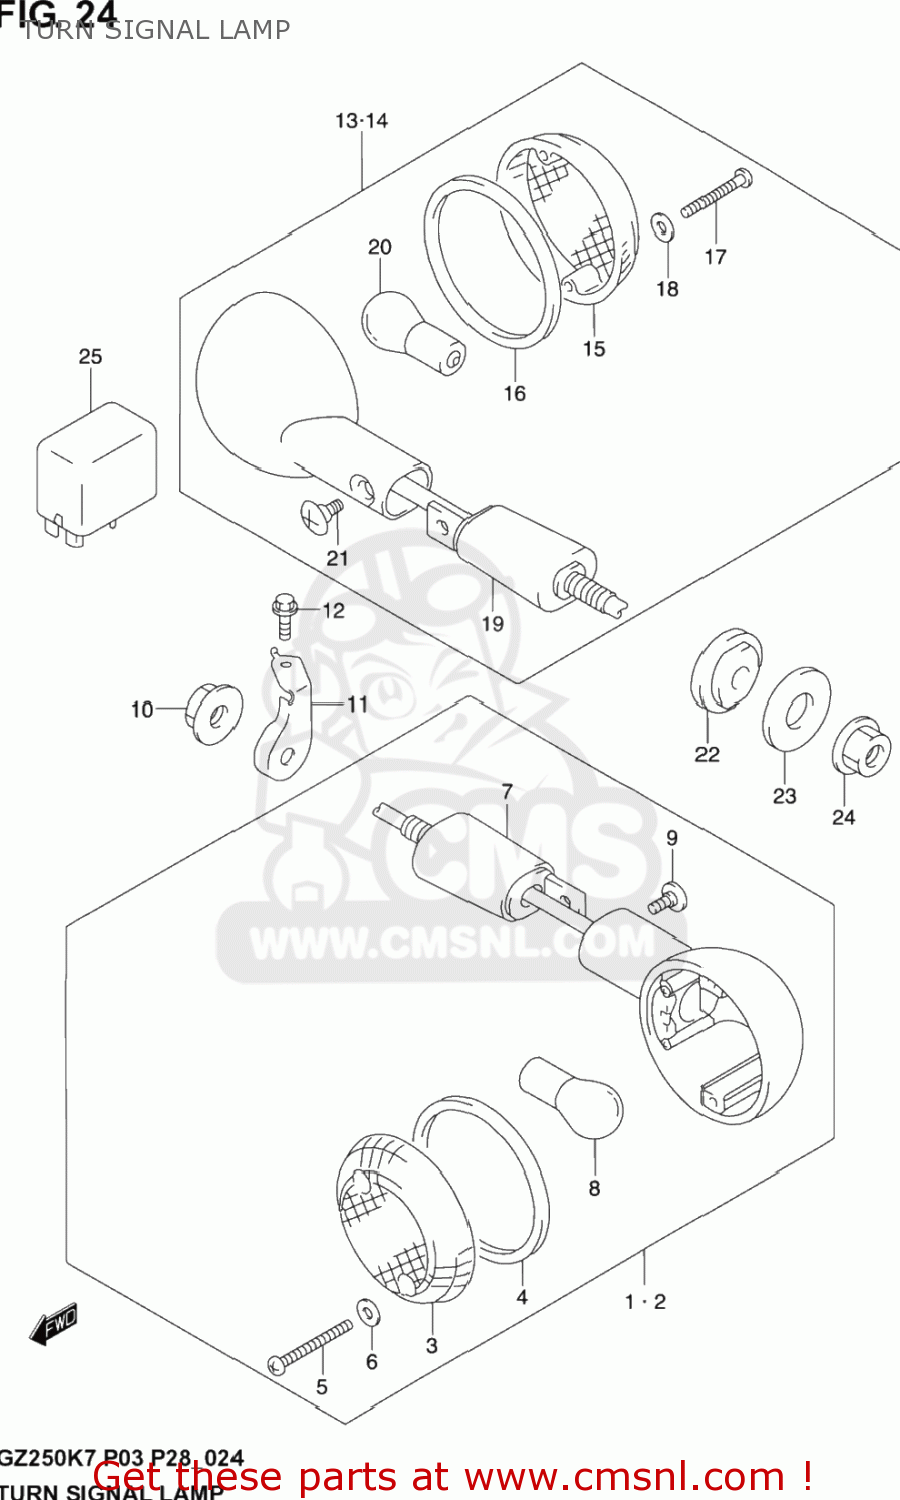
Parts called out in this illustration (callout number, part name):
1	LAMP ASSY,FR TURN SIGNAL,R
2	LAMP ASSY,FR TURN SIGNAL,L
3	LENS
4	GASKET (NAS)
5	SCREW
6	GASKET (NAS)
7	STAY,TURNSIGNAL FR
8	BULB(12V21/5W)
9	SCREW
10	NUT
11	BRACKET,FR TURNSIGNAL,R
12	BOLT
13	LAMP ASSY,RR TURNSIGNAL,R
14	LAMP ASSY,RR TURNSIGNAL,L
15	LENS
16	GASKET (NAS)
17	SCREW
18	GASKET (NAS)
19	STAY,TURNSIGNAL RR
20	BULB(12V21W)
21	SCREW
22	SPACER,RR TURNSIGNAL
23	WASHER(10.5X30X2.3)
24	NUT
25	RELAY ASSY,TURNSIGNAL LAMP
